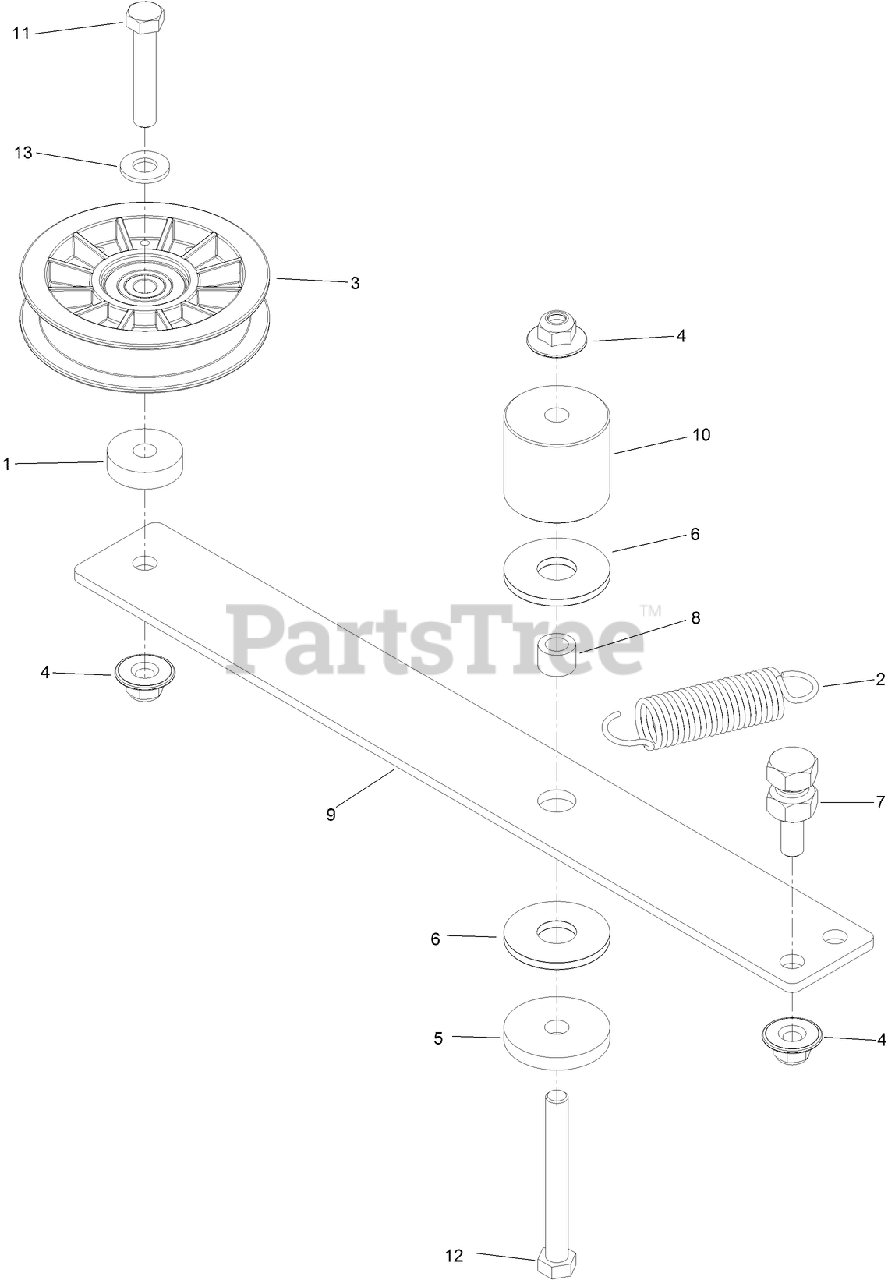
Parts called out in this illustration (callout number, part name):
1	Spacer
2	SPRING-EXTENSION
3	PULLEY-IDLER, FLAT
4	NUT-FLANGE, NI
5	WASHER-PLAIN
6	WASHER-FRICTION, COMPOSITE
7	ANCHOR-SPRING, SHORT
8	SPACER
9	ARM-IDLER, HYDRO
10	SPACER-PLAIN
11	SCREW-HH
12	SCREW-HH
13	WASHER-FLAT
